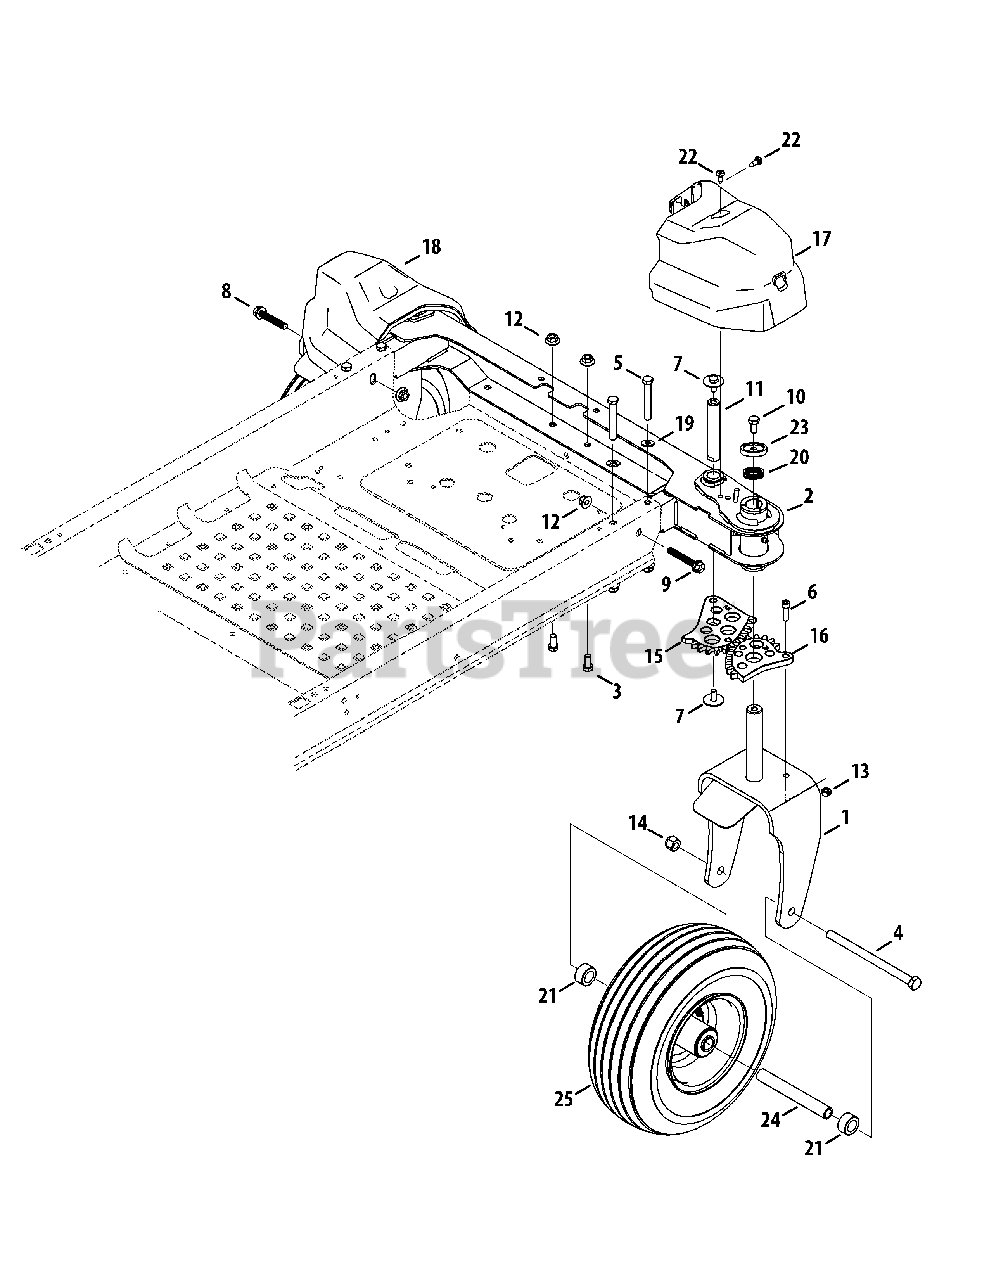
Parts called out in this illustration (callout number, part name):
1	Caster Wheel Bracket
2	Front Axle
3	Hex Cap Screw, 3/8-16 x .75
4	Bolt, 1/2-20 x 7.25
5	Screw, 3/8-16 x 2.75
6	Socket Head Screw, 5/16-18 x 1.00
7	Hex Cap Screw, 5/16-18 x .75
8	Hex Flange Screw, 3/8-16 x 2.25
9	Hex Flange Screw, 3/8-16 x 2.00
10	Hex Screw, 3/8-16 x .75
11	Pivot Gear Steering Shaft
12	Flange Lock Nut, 3/8-16
13	Hex Lock Nut, 5/16-18
14	Hex Lock Nut, 1/2-20
15	12-Tooth Variable Gear
16	13-Tooth Variable Spur Gear
17	Axle Cover, RH
18	Axle Cover, LH
19	Flat Washer, .385 x .870 x .092
20	Wave Washer, 1.25 x 1.00 x .300
21	Spacer, .76 x 1.23 x .63
22	Shoulder Screw, 1/4-20
23	Shoulder Spacer, 1.75 x .180
24	Spacer, .51 ID x .75 OD x 5.825
